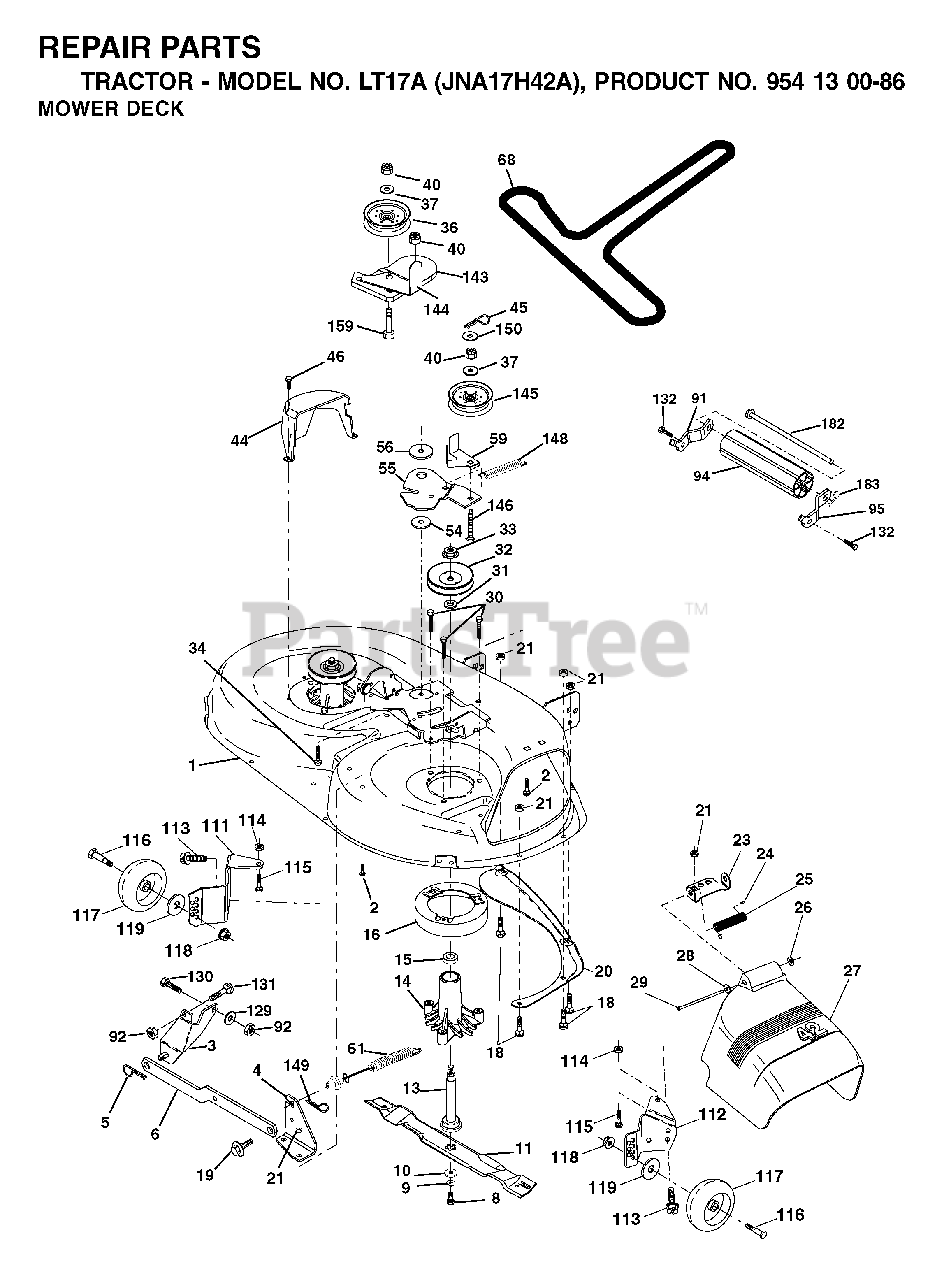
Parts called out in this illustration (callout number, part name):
1	42" DECK KIT
2	BOLT
3	BRKT ASM SWAY BAR
4	BRACKET SWAY BAR 42" DECK
5	RETAINER-SPRNG RB
6	BAR SWAY DECK
8	BLADE BOLT
9	LOCKWASHER
10	WASHER.BLADE
11	BLADE 42"
13	SHAFT ASM VENT
14	HSG MANDREL
16	STRIPPER, MWR ROUND
18	BOLT
19	BOLT SHD 5/16-18
20	BAFFLE.VORTEX
21	LOCKNUT
23	BRKT, DEFL. MOWER
24	CAP-SLEEVE LT
25	SPRING TORSION
26	NUT PUSH M
27	SHIELD DEFLECTOR
28	WASHER
29	ROD.HINGE
30	SCREW, WASHER HEAD
31	WASHER
32	PULLEY/MANDREL
33	NUT, FLG TOPLOCK 9/16"
34	BOLT
36	FLAT IDLER PULLEY
40	LOCKNUT
44	GUARD MANDREL LH BLACK
45	RETAINER M
46	SCREW.1/4-20X5/8
54	HARDENED WASHER
55	ARM IDLER 42" MOWER LT/YT
56	SPACER.RETAINER.MOWER
59	GUARD, BELT
61	SPRING EXT ELEC CLUTCH
68	V-BELT PRIMARY 42"
91	BRACKET ASM NOSEROLLER LH
92	NUT.71038.31-18.HEX.NYLOCK
94	NOSE ROLLER
95	BRACKET ASM NOSEROLLER RH
111	BRACKET, WHEEL
112	BRACKET, WHEEL
113	SCREW.3/8-16X.625
114	NUT
115	BOLT
117	WHEEL.GAUGE.STANDARD
118	LOCKNUT
119	WASHER
129	WASHER
131	BOLT D
132	SCREW 3/8-16X3/4
143	BRACKET, ARM IDLER
144	KEEPER.BELT.42".CLUTCH.CABLE
145	PULLEY
146	BOLT, CARRIAGE IDLER BLACK
148	IDLER RETURN SPRING
149	SPRING.RETAINER.YELLOW.ZINC
150	WASHER PM
159	BOLT
182	ROD ROLLER NOSE STANDARD
183	SPRING RETAINER
5321341-49	BLADE.42".MULCH
